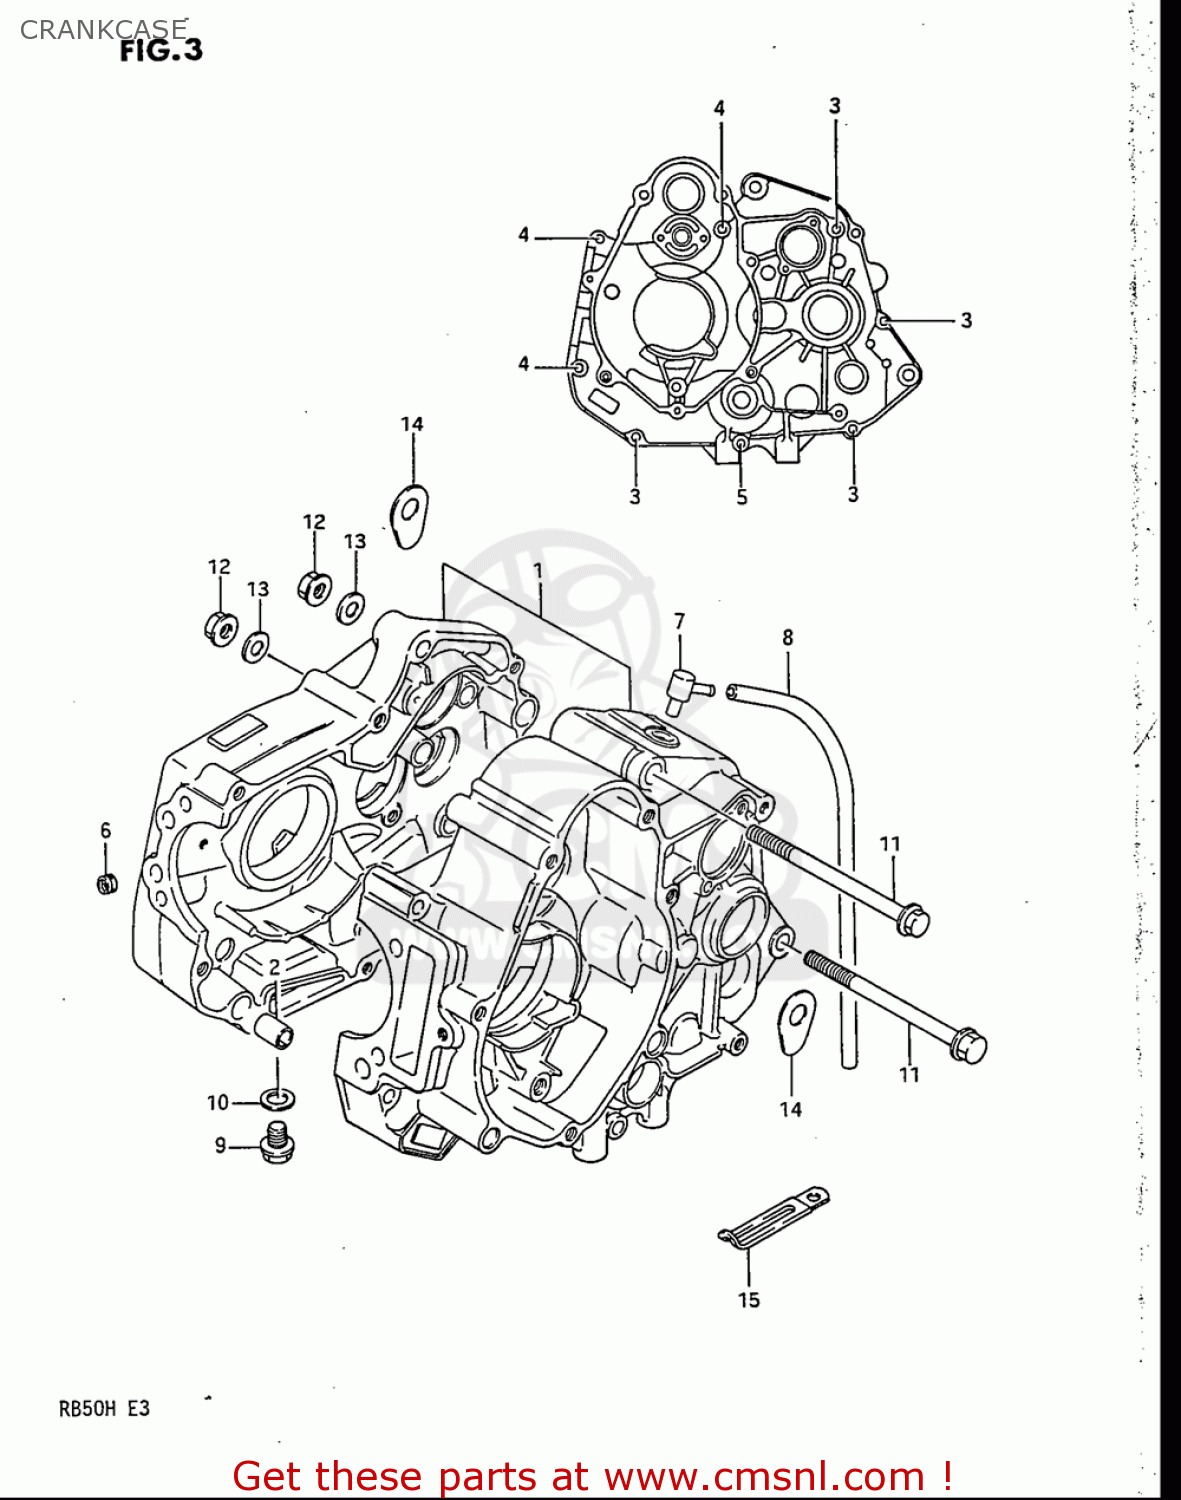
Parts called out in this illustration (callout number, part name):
2	PIN
3	SCREW
4	SCREW
5	SCREW
7	UNION,BREATHER HOSE
8	HOSE
9	PLUG
10	GASKET(10X14X3.6) (NAS)
11	BOLT(8X100)
12	NUT
13	WASHER
14	SHIM (T:0.3)
15	CLAMP(L:65)
